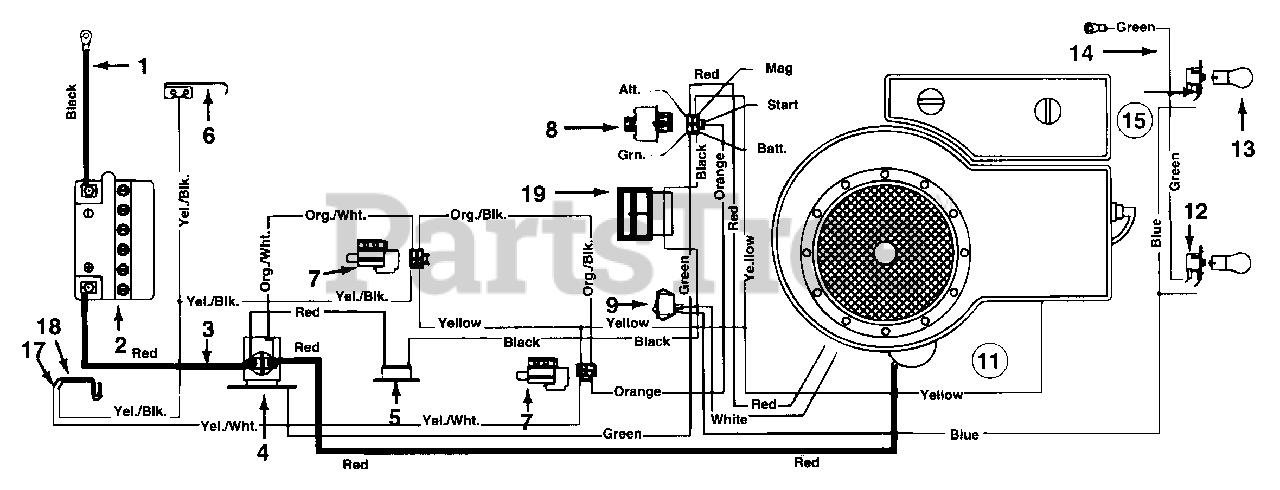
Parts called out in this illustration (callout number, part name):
1	Ground Wire
2	Battery
3	Electric Wire - 8.0" Lg.
4	Solenoid
5	Circuit Breaker
6	Spring Switch
7	Safety Switch
8	Ignition Switch
9	Light Switch
11	Harness w/Amp & Light Switch
12	Socket
13	Bulb
14	Ground Wire
15	Headlight Harness w/Amp & Light Switch
15	Headlight Harness
17	Safety Switch (Seat)
18	Safety Switch (Seat)
19	Ammeter
